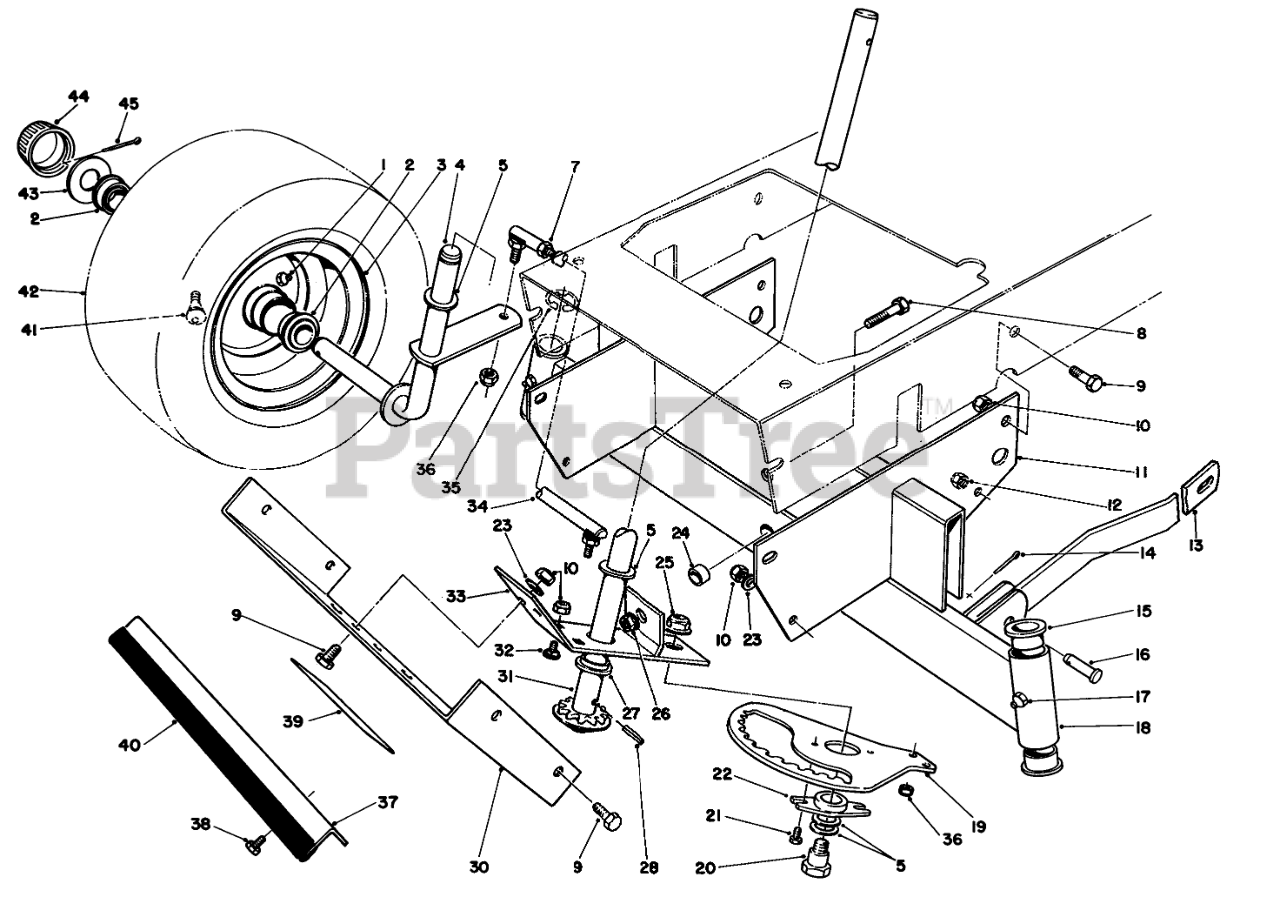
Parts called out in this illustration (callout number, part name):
1	FITTING-GREASE
2	Bearing
4	Spindle RH
5	WASHER-THRUST
7	NUT-JAM
8	SCREW-HH
9	SCREW-HH
10	NUT-LOCK, NI
11	Support
12	NUT-HEX
13	Arm-Suspension, Front
14	PIN-COTTER
15	BEARING-FLANGE
16	PIN-CLEVIS
17	GREASE FITTING
18	Axle-Front (Incl. Ref. #15 & 17)
19	Rack-Steering
21	SCREW-HWH
22	BUSHING-SECTOR
23	WASHER-PLAIN
24	SPACER-AXLE, FRONT
25	NUT-HF
26	NUT-HF
27	BEARING-FLANGE
28	PIN-ROLL, SLOTTED
30	Cover-Front
31	STRG SHAFT WA
32	SCREW-CARR
33	Bracket-Rack, Steering (Incl. Ref. #27)
34	Tie Rod-Adjustable (Incl. Ref. #7)
35	E-RING
36	NUT-LOCK
37	FRONT GUARD R
38	SCREW-HWHTF
39	Decal-Warning
40	TRIM-FRONT GUARD
41	Stem-Valve
42	TIRE,PNEU.11X4.00X5
43	WASHER-PLAIN
44	CAP-HUB
45	PIN-COTTER
